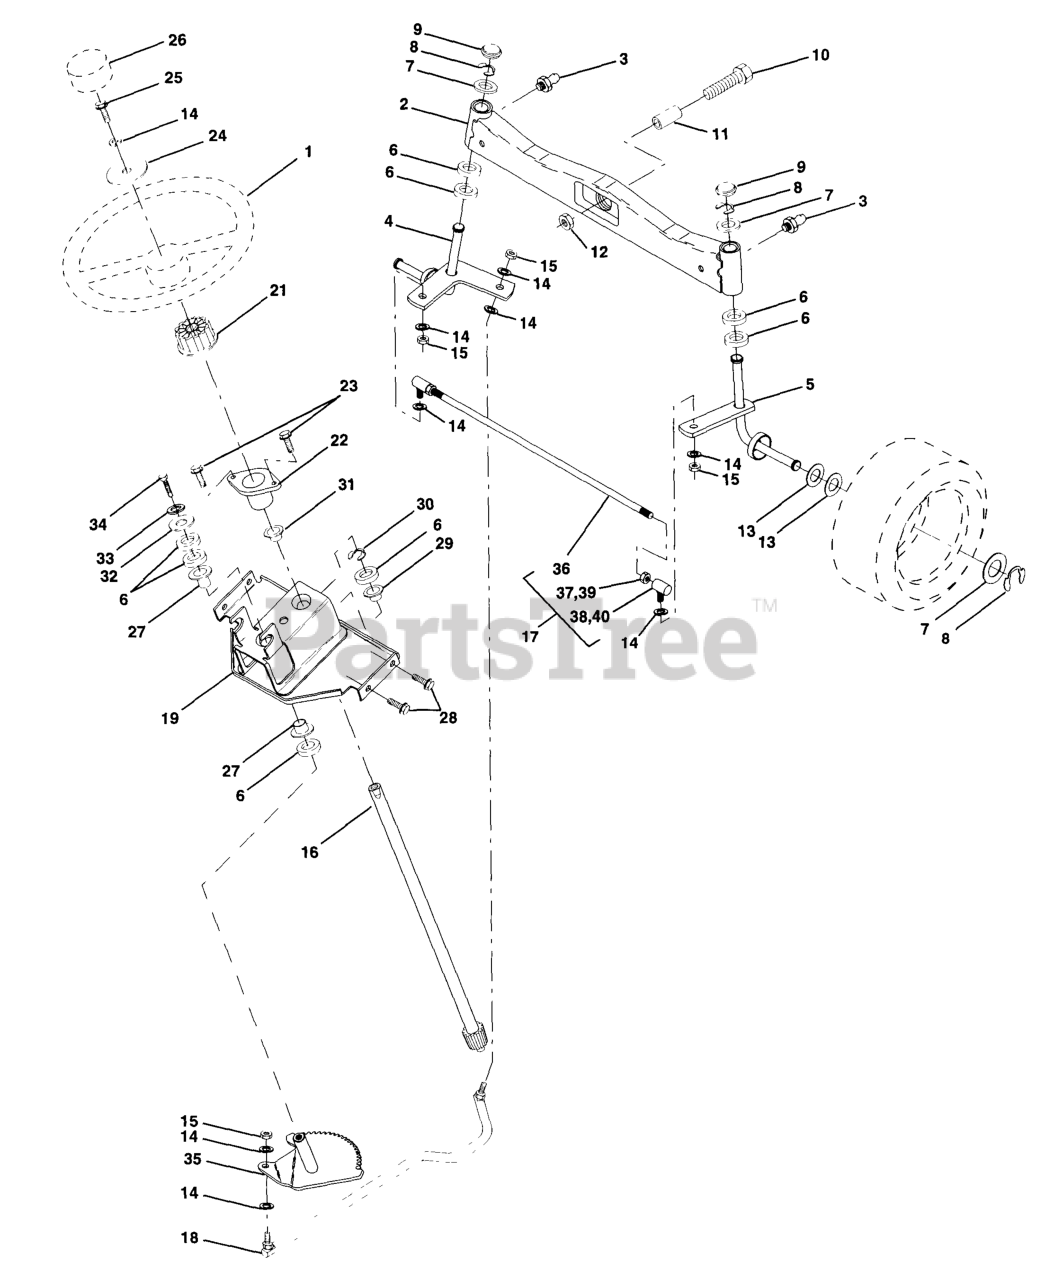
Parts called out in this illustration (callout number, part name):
1	STEERING WHEEL
2	FRONT AXLE ASSY
3	ZERK M
4	SPINDLE ASSY LH
5	SPINDLE ASSY RH
6	THRUST WASHER
9	CAP.SPINDLE.BLACK
10	Bolt, Fin Hex 5/8-11 x 2-3/4
11	TUBE, PIVOT AXLE
12	NUT-LOC,FLANGE LT
14	WASHER, LOCK 3/8
15	GRIPCO NUT
16	SHAFT ASM, STEERING
17	ROD ASSY/TIE BALL
18	DRAGLINK-BALL JOINT SOLID
19	SUPPORT ARM, STEERING VGT
21	ADAPTER LT
22	BUSHING, STRG. BLK
23	SCREW.TT.#10-32X.5.3/8.FLANGE
24	WASHER T
25	BOLT
26	INSERT,STR WHEEL
27	BRNG T
28	SCREW
29	BEARING-FLANGE GT
30	Ring, Klip Truarc #5304-75
31	BUSHING.NYLINER.
33	WASHER.LOCK.HVY.HLCL.SPR.5/16
34	BOLT
35	GEAR.ASM.SECTOR.
36	TIE ROD
38	JOINT
